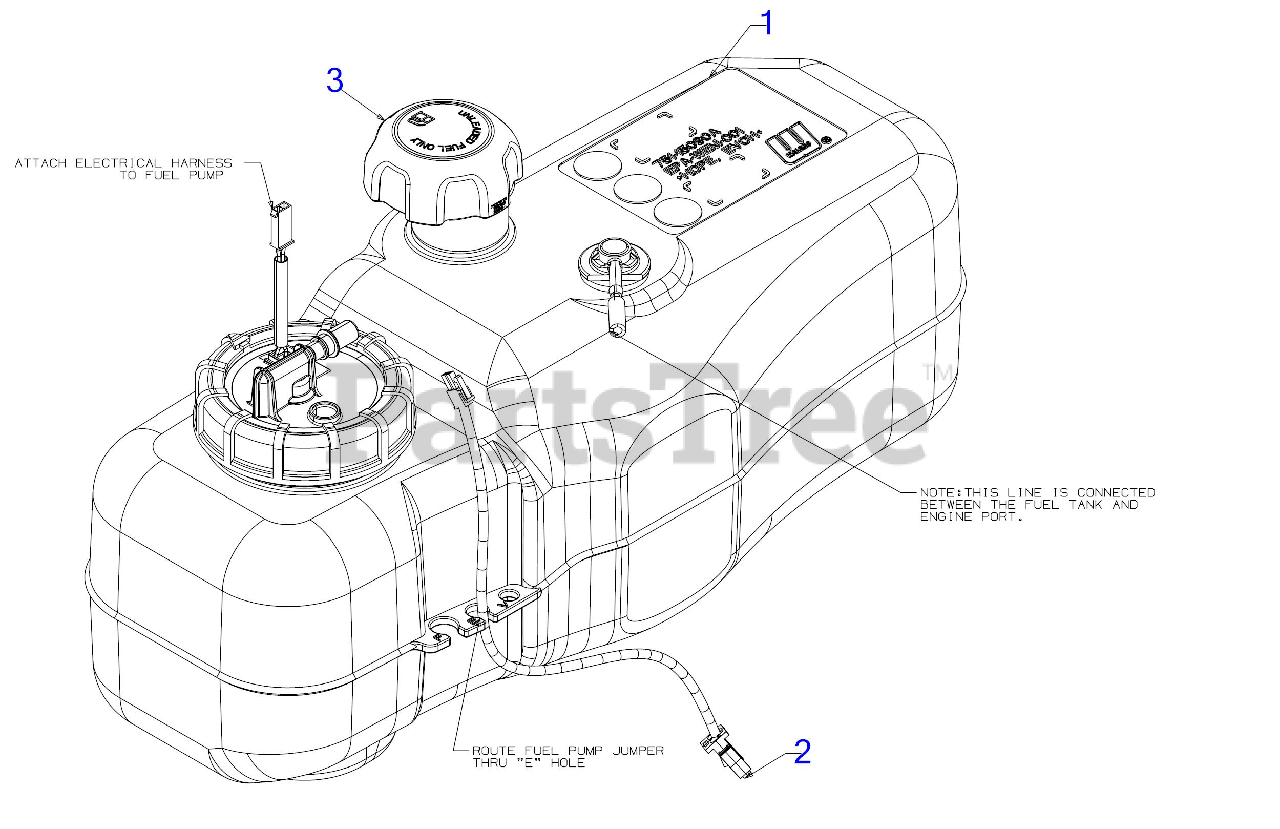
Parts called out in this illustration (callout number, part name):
1	EFI FUEL TANK ASSEMBLY (3.5 GAL)
2	EFI TANK JUMPER HARNESS
3	FUEL CAP W/TETHER
